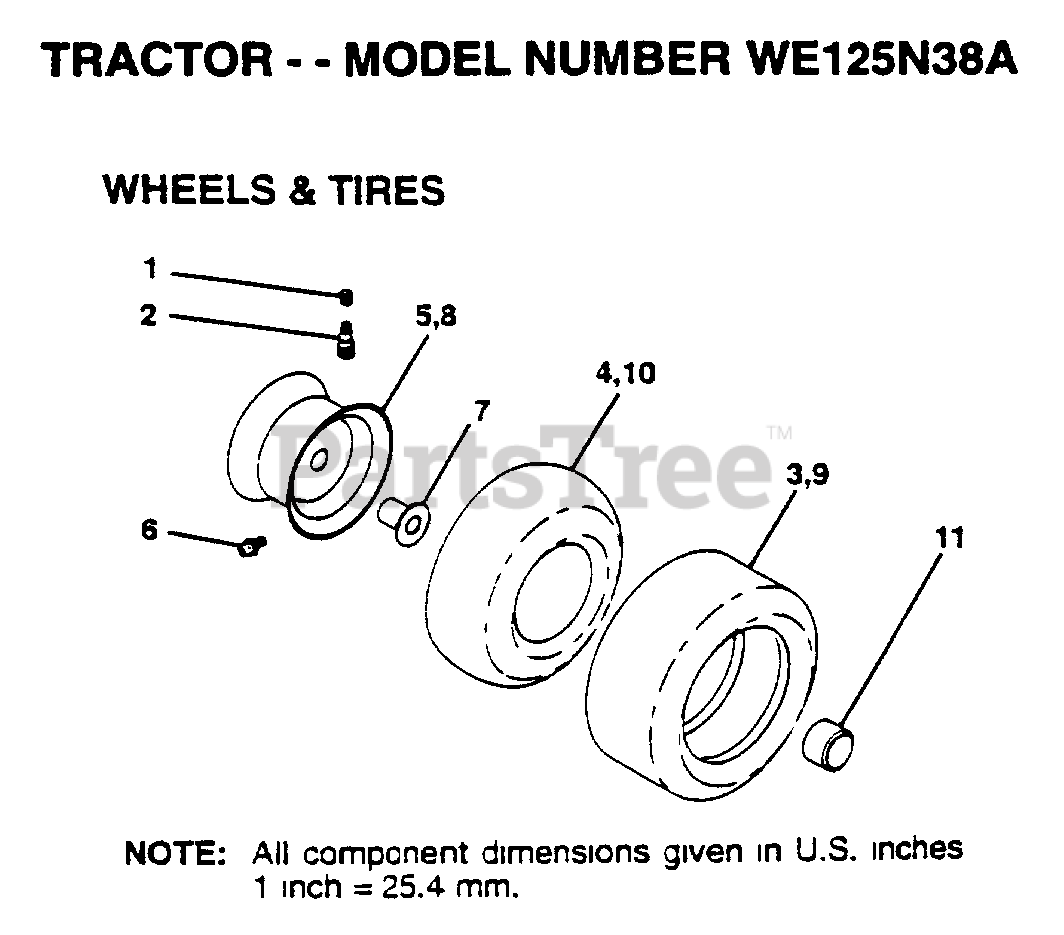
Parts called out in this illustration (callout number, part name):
1	VALVE CAP
2	VALVE STEM LT
4	TUBE.5.3/4.5/6
5	"RIM.ASM.6""FRONT"
6	FITTING LT
7	"FLANGE, BEARING"
8	"RIM.ASM.8""REAR"
10	TUBE.18X9.5-8
11	HUB CAP
